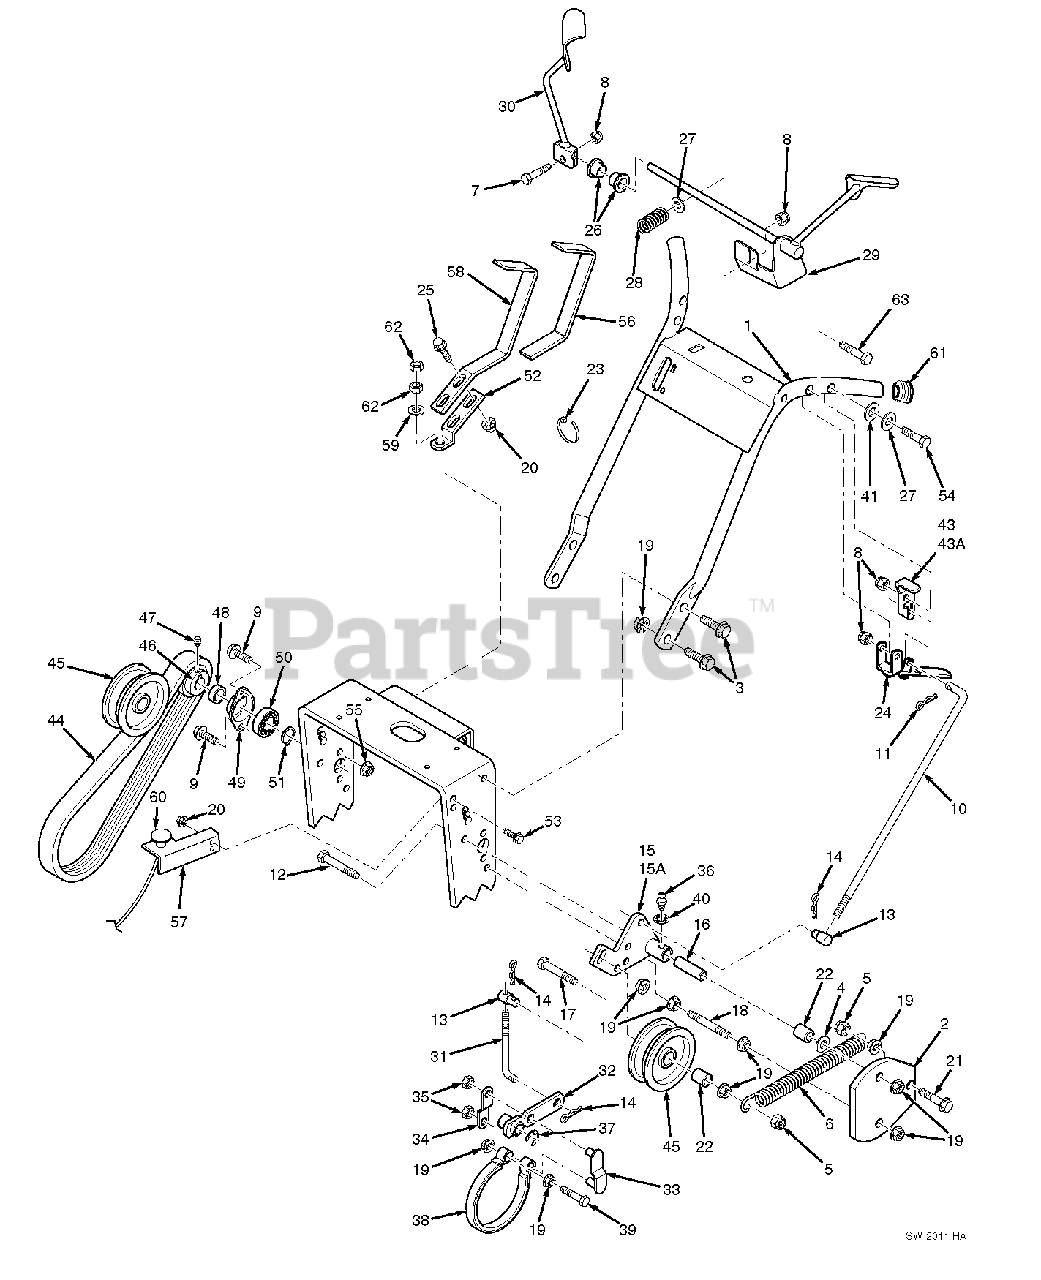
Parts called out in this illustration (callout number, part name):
1	Handle Assembly
2	Belt Guard
3	Capscrw, 3/8-16 x 1" Serr. Flg.
4	Washer, 3/8"
5	Nut, 3/8-16 Elastic Stop
6	Spring, Idler
7	Bolt, 5/16-18 x 1-1/4" Hex Head
8	Nut, 5/16-18 Elastic Stop
9	Capscrew, 1/4-20 x 3/4" Hex Head
10	Control Rod, Steering
11	Hair Pin, Small
12	Bolt, 3/8-16 x 4-1/2" Hex Head
13	Swivel Joint
14	Hair Pin, Large .094 Dia.
15	Idler Bracket, RH
15A	Idler Bracket, LH
16	Idler Sleeve
17	Bolt, 3/8-16 x 3/4" Hex Head
18	Stud, 3/8-16 x 5"
19	Nut, 3/8-16 Serrated Flange
20	Nut, 5/16-18 Serrated Flange
21	Cpscrw, 3/16-18 x 1-1/4" Serr. Flg
22	Spacer
23	Cable Tie
24	Steering Lever
25	Capscrew, 5/16-18 x 1" Serr. Flg.
26	Bushing
27	Washer, 5/16
28	Spring, Operator Presence
29	Operator Presence Lever, LH
30	Operator Presence Lever, RH
31	Brake Rod
32	Brake Lever
33	Brake Link
34	Brake Link Plate
35	Nut, 3/8 Push-on
36	Grease Fitting, Straight 1/4-28
37	Retaining Ring, 5/8 Ext. "E"
38	Brake Band
39	Bolt, 3/8-16 x 2" Hex Head
40	1/4" Internal Tooth Lockwasher
41	Socket Head Capscrew #8-32 x 1/2"
42	Socket Head Capscrew #8-32 x 1/2"
43	Neutral Latch, RH
43A	Neutral Latch, LH
44	Belt, Wheel Drive
45	Idler Pulley, Wheel Drive
46	Pulley, Jackshaft
47	Setscrew, Hex Socket Knurl Cup Pt. 5/16-18
48	Spacer, Jackshaft Pulley
49	Flange, Jackshaft Bearing
50	Bearing, Jackshaft
51	Retaining Ring, 5/8 Ext. Basic
52	Shift Lever
53	Capscrew, 5/16-18 x 3/4" Serr. Flg.
54	Bolt, 5/16-18 x 2" Hex Head
55	Nut, 1/4-20 Serrated Flange
56	Grip, Shift Handle
57	Bracket, Choke Mounting
58	Shift Lever Extention
59	Washer, 3/8
60	Choke Control
61	Plug, Handlebar
62	Nut, 3/8-24 UNF
63	Bolt, 5/16-18 x 2-1/2"
64	Fuel Tank Cap
